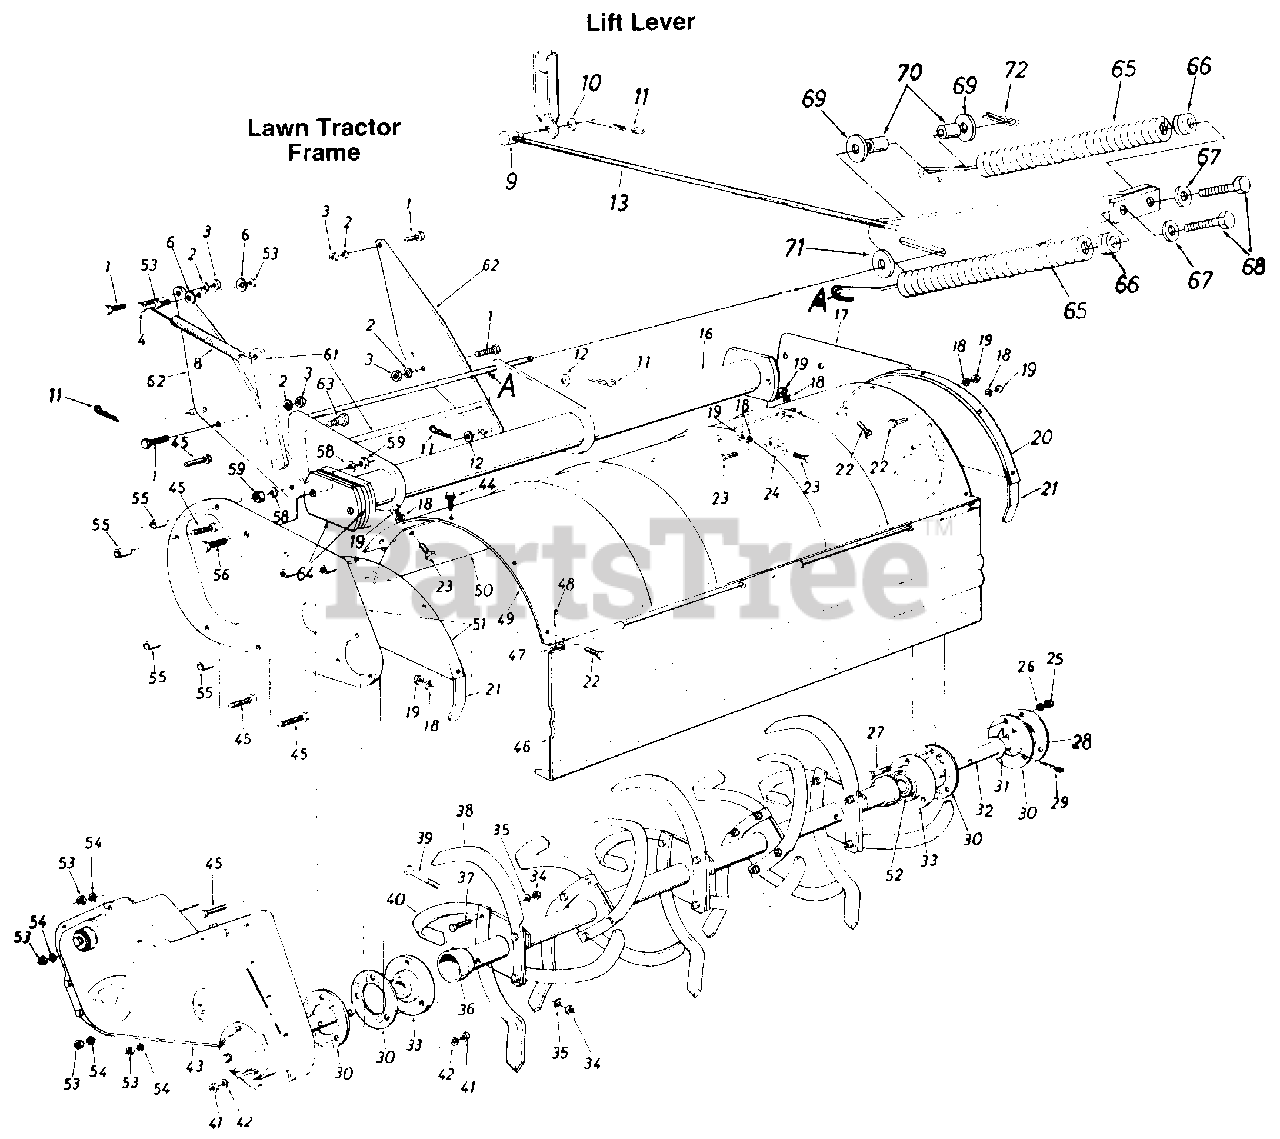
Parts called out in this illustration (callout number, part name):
1	Hex Bolt 3/8-24 x .88" Lg.
2	L-Wash. 3/8" I.D.- H.D.
3	Hex Nut 3/8-24 Thd.
4	Hex Bolt 1/4-20 x 1.25" Lg.
6	Bell-Wash. 1/4" I.D.
8	Ext. Spring 7.75" Lg.
9	Adjustment Ferrule 1/2-13 Thd.
10	Fl-Wash..64" I.D. x 1.24" O.D. x .06"
11	Intern. Cotter Pin 1/2" Dia.
12	Fl-Wash..51" I.D. x 1.0" O.D. x .06"
16	Pivot Bracket Assembly
19	Hex Nut 5/16-24 Thd.
23	Hex Bolt 5/16-24 x .62" Lg.
24	Chute Pivot Bracket
25	Hex L-Nut 5/16-18 Thd.
27	Hex Bolt 5/16-18 x 1" Lg. (Grade 5)
30	Gasket for Brg. Housing
31	Fl- Wash. 1.25" I.D. x 2.0" O.D. x 06"
32	Tine Shaft 1.25" Dia. x 6.25" Lg.
33	Bearing Housing w/ Bearing
43	Chain Case Ass'y. Comp.
44	Hex TT-Tap Scr. 5/16-18 x .62" Lg.
45	Hex Bolt 1/4-20 x 2.75" Lg.
48	Cotter Pin 1/8" Dia. x 1" Lg.
53	Hex Nut 1/4-20 Thd.
54	L-Wash. 1/4" I.D.
55	Spacer .28" I.D. x .62" O.D. x .9" Lg.
56	Hex Bolt 1/2-20 x 1.5" Lg.
58	L-Wash. 1/2" I.D.
59	Hex Nut 1/2-20 Thd.
61	Idler Brkt. Support Arm Ass'y.
64	Support Plate
65	Helper Spring
66	Spring Insert
67	Fl-Wash..34" I.D. x .68" O.D.
68	Hex Bolt 5/16-18 x 3.25" Lg.
69	Fl-Wash..51" I.D. x 1.5" O.D.
70	Split Spacer .505" I.D. x .57" Lg.
71	Fl-Wash..531" I.D. x 1.25" O.D.
72	Internal Cotter Pin 1/2" Dia.
